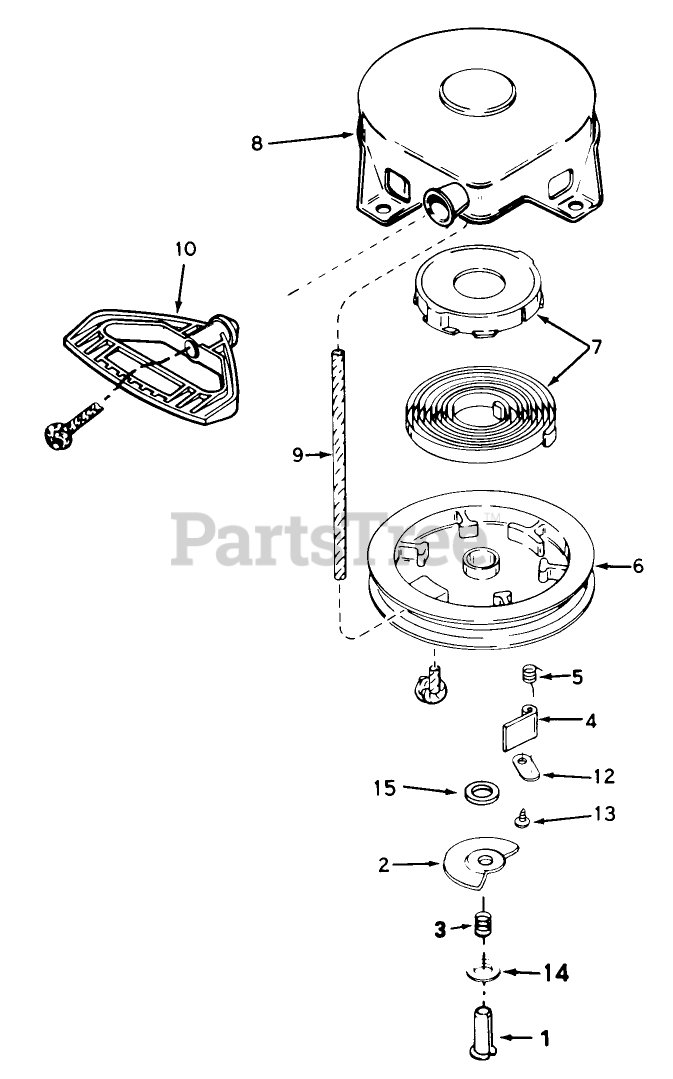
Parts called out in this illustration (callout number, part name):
1	Pin, Spring (Incl. Ref. #7)
2	Washer
3	Brake Spring
4	Dog-Starter
5	Spring-Dog
6	Pulley
7	Spring Keeper Assy
8	Housing-Starter
9	Rope-Starter
10	Handle-Starter, Mitten Grip
12	Retainer-Dog
13	Screw
14	Washer
15	Washer
